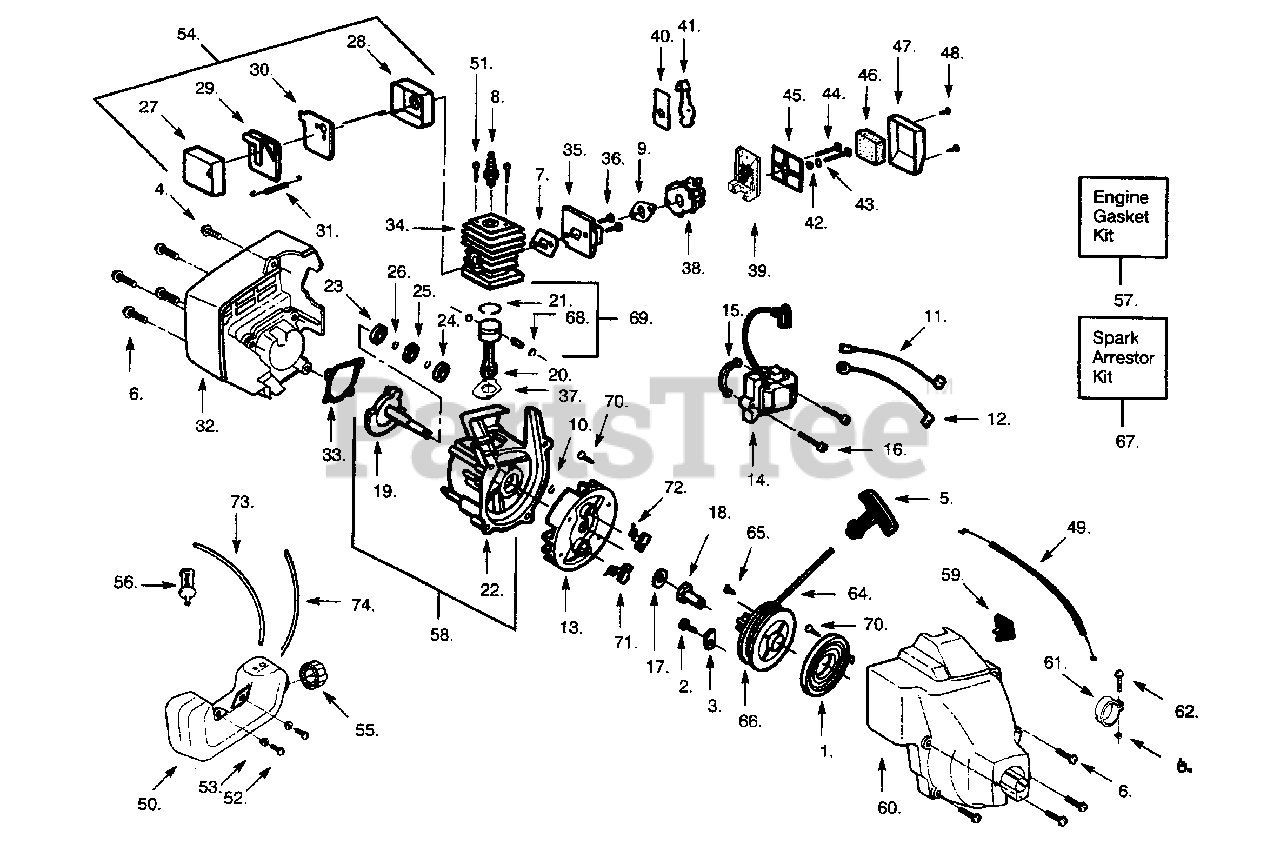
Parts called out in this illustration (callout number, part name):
1	Starter Spring
2	Screw-Pulley
3	Retainer-Pulley
4	Screw-Shrd/Fan Hsg.
5	Starter Handle
6	Screw
7	Gasket-Cylind./Carb.
8	Spark Plug (RCJ 8Y)
9	Gasket-Carb.
10	RetainerRing-C'case
11	Lead Wire
12	Ground Wire
13	Flywheel
14	Ignition Module
15	Spacer- Ignit. Module
16	Screw-Ignit. Module
17	Washer-Thrust
18	Drive Coupling
19	Crankshaft Ass'y.
20	Connecting Rod Ass'y.
21	Piston Ring
22	Crankcase Ass'y.(Incl 23-26)
23	Inner Bearing
24	Outer Bearing
25	C'case Seal
26	Retain. Ring-C'shaft
27	Muffler Body
28	Muffler Cover
29	Muffler Baffle-Exit
30	Muffler Baffle-First
31	Muffler Spring
32	Rear Shroud
33	Gasket-C'case
34	Cylinder Kit
35	Carb. Adaptor
36	Screw-Carb Adaptor
37	Gasket-Cylinder
38	Carburetor Kit-WT 223 (Incl. Limiter Cap and Primer Bulb Ass'y)
40	Choke Plate
41	Choke Shutter
42	Wave Washer
43	Choke Spacer
44	Screw-Carburetor
45	Filter Plate
46	Air Filter Foam
47	Air Filter Cover
48	Screw-Air Box
49	Throttle Cable Ass'y.
50	Fuel Tank Ass'y
51	Screw-Cylinder
52	Screw-Fuel Tank
53	Washer- Fuel Tank
54	Muffler Kit
55	Fuel Cap Ass'y.
56	Fuel Pickup Ass'y.
57	Engine Gasket Kit (Incl. 7,9,33,37)
58	C'case & C'shaft Assy. (Incl. 10, 19,22-26)
59	On/Off Switch
60	Fan Housing Ass'y
61	Clamp-Nose Cone
62	Screw-Nose Cone
63	Nut-Nose Cone
64	Rope Kit
65	Screw-Rope Retain.
66	Starter Pulley Kit (Incl. 65)
67	Spark Arrestor Kit
68	Piston Pin Retainer
69	Piston Kit (Incl. 21,68 & Pin)
70	Screw-Flywheel
71	Starter Dog
72	Starter Dog Spring
73	Fuel Line-Carb./Tank
74	Fuel Line-Prim./Tank
